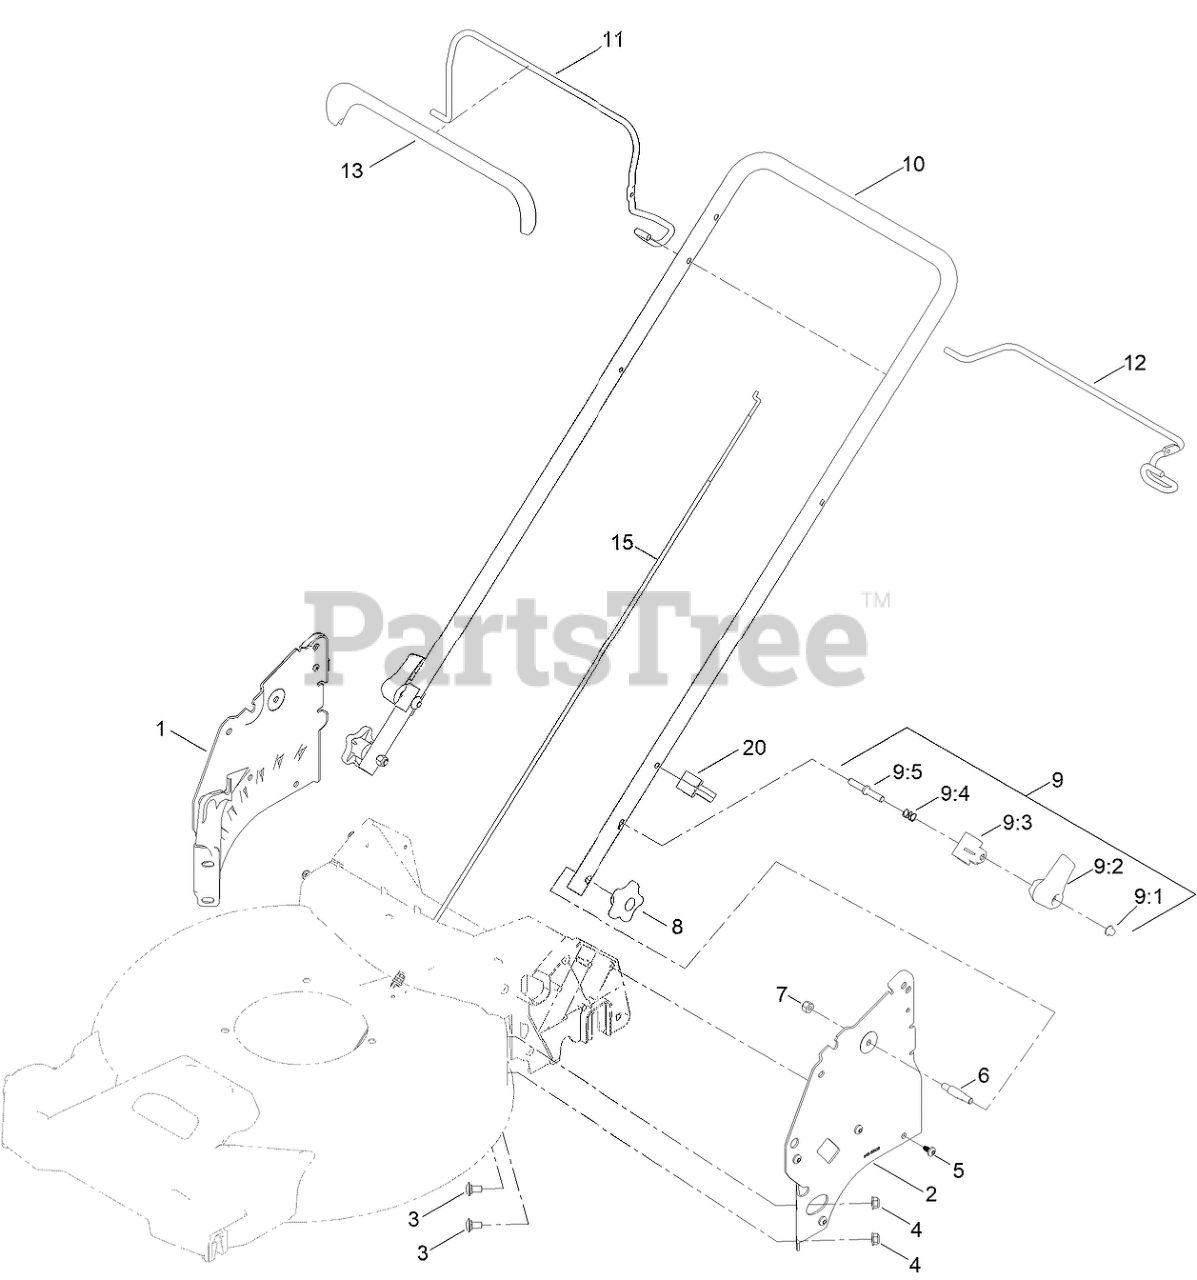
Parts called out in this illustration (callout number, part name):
1	PLATE-HANDLE, RH
2	PLATE-HANDLE, LH
3	SCREW-CARR
4	NUT-FLANGE, NI
5	SCREW-PLASTIC,PH
6	BOLT-SHOULDER, HANDLE
7	NUT-LOCK, NI
8	KNOB-HANDLE
9	QUICK RELEASE ASM
9:1	NUT-PUSH
9:2	LEVER-RELEASE
9:3	ANCHOR-SPRING
9:4	SPRING-COMPRESSION
9:5	ROD-RELEASE
10	HANDLE-UPPER
11	BAIL-BRAKE
12	BAIL-TRACTION
13	COVER-BAIL
15	CABLE-TRACTION
20	GUIDE-CABLE
